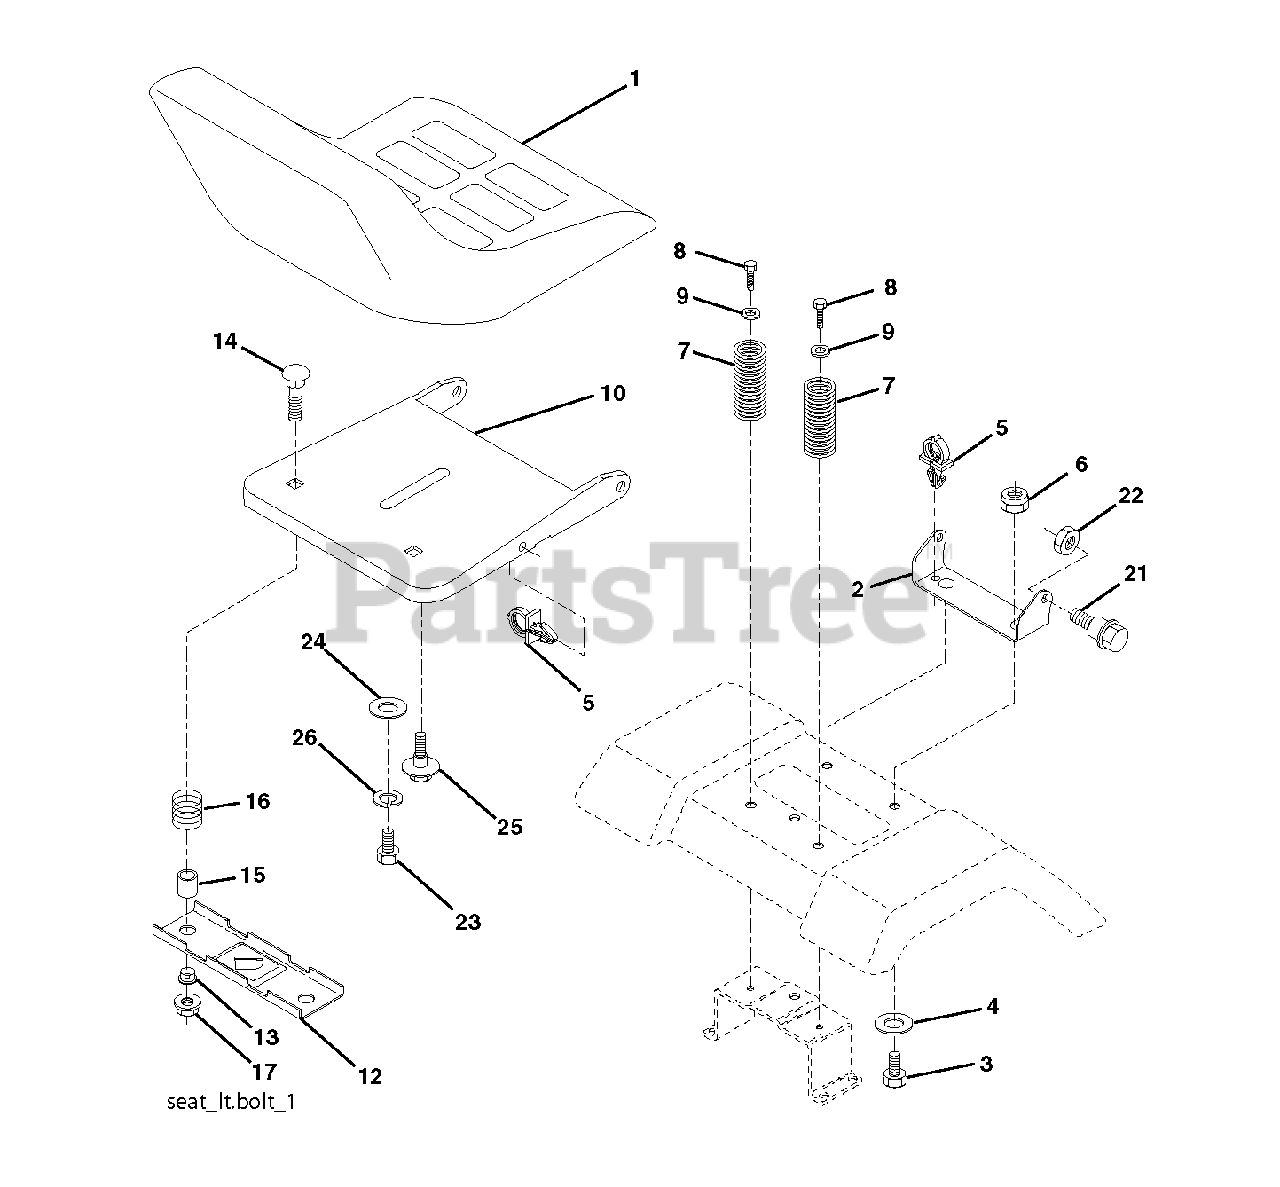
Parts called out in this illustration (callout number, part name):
1	SEAT.XG090.BLK.KB/BLT.NO-LOG
2	SEAT PIVOT BRKT
4	WASHER PM
5	PUSH CLIP
6	NUT
7	SPRING COMPRESSION
8	SCREW 3/8-16X1
9	WASHER
10	PAN.ASM.SEAT.1SLOT
12	BRKT.MNTNG.SWITCH.SEAT
14	BOLT.ROUND.HEAD.SQUARE.NECK
15	SPACER SPLIT 28X.96
17	NUT T
21	BOLT.SHOULDER.5/16-18
22	NUT.71038.31-18.HEX.NYLOCK
23	BOLT.HEX.BLACK
25	BOLT,SHOULD
26	LOCKWASHER
